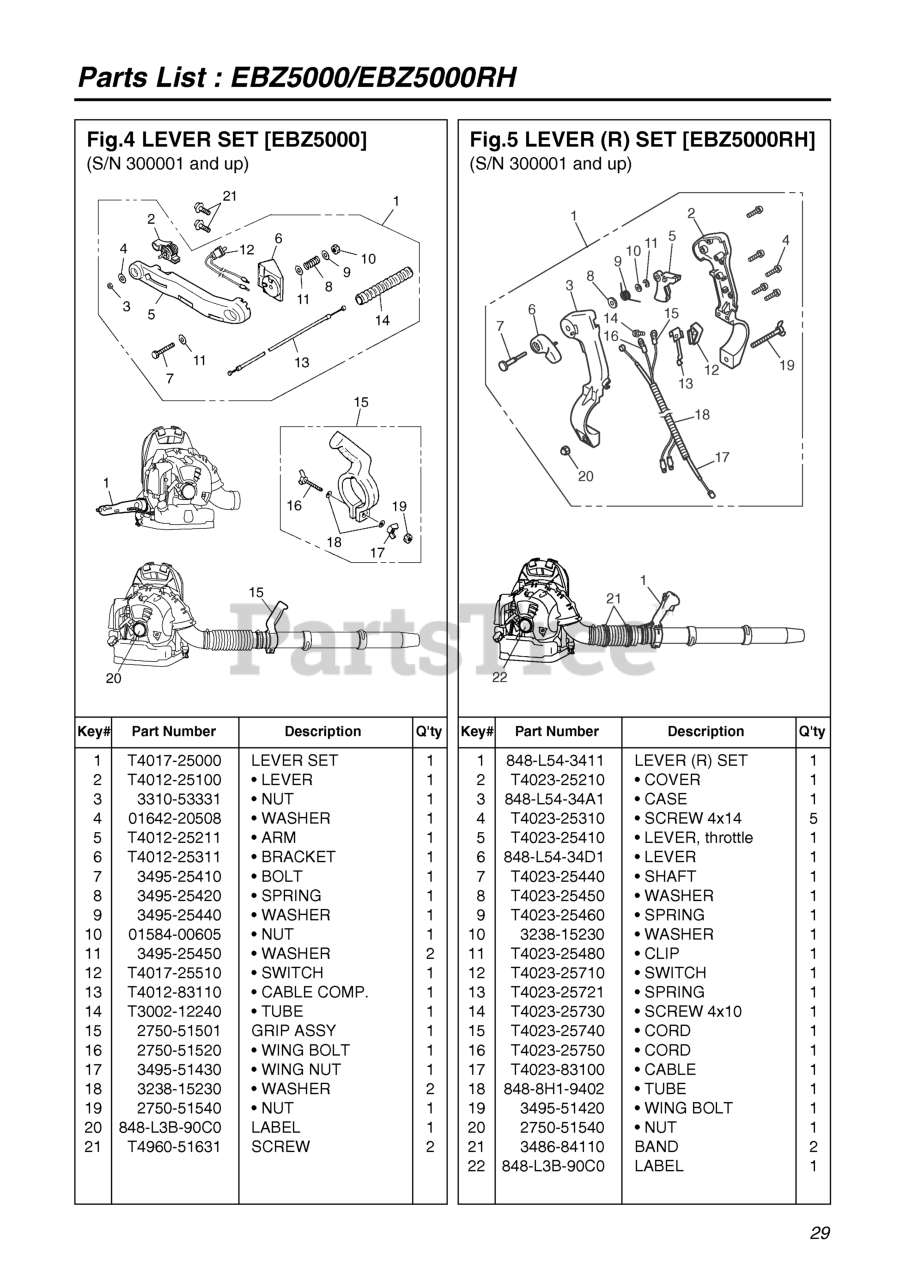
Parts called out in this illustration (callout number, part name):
1	LEVER SET
2	LEVER
3	NUT (B)
4	WASHER, M5x.8(RPLS 01624-20508
5	ARM (RPLS T4012-25210)
6	BRACKET (RPLS -25310)
7	BOLT
8	SPRING
9	WASHER
10	NUT, M6 X 5
11	WASHER, FLAT
12	SWITCH
13	CABLE COMPLETE
14	TUBE (RPLS 4900-72141)
15	GRIP ASSEMBLY (RPLS -51500)
16	WING BOLT
17	NUT, WING
18	WASHER
19	NUT
20	LABEL, RECOIL
21	SCREW TORX
